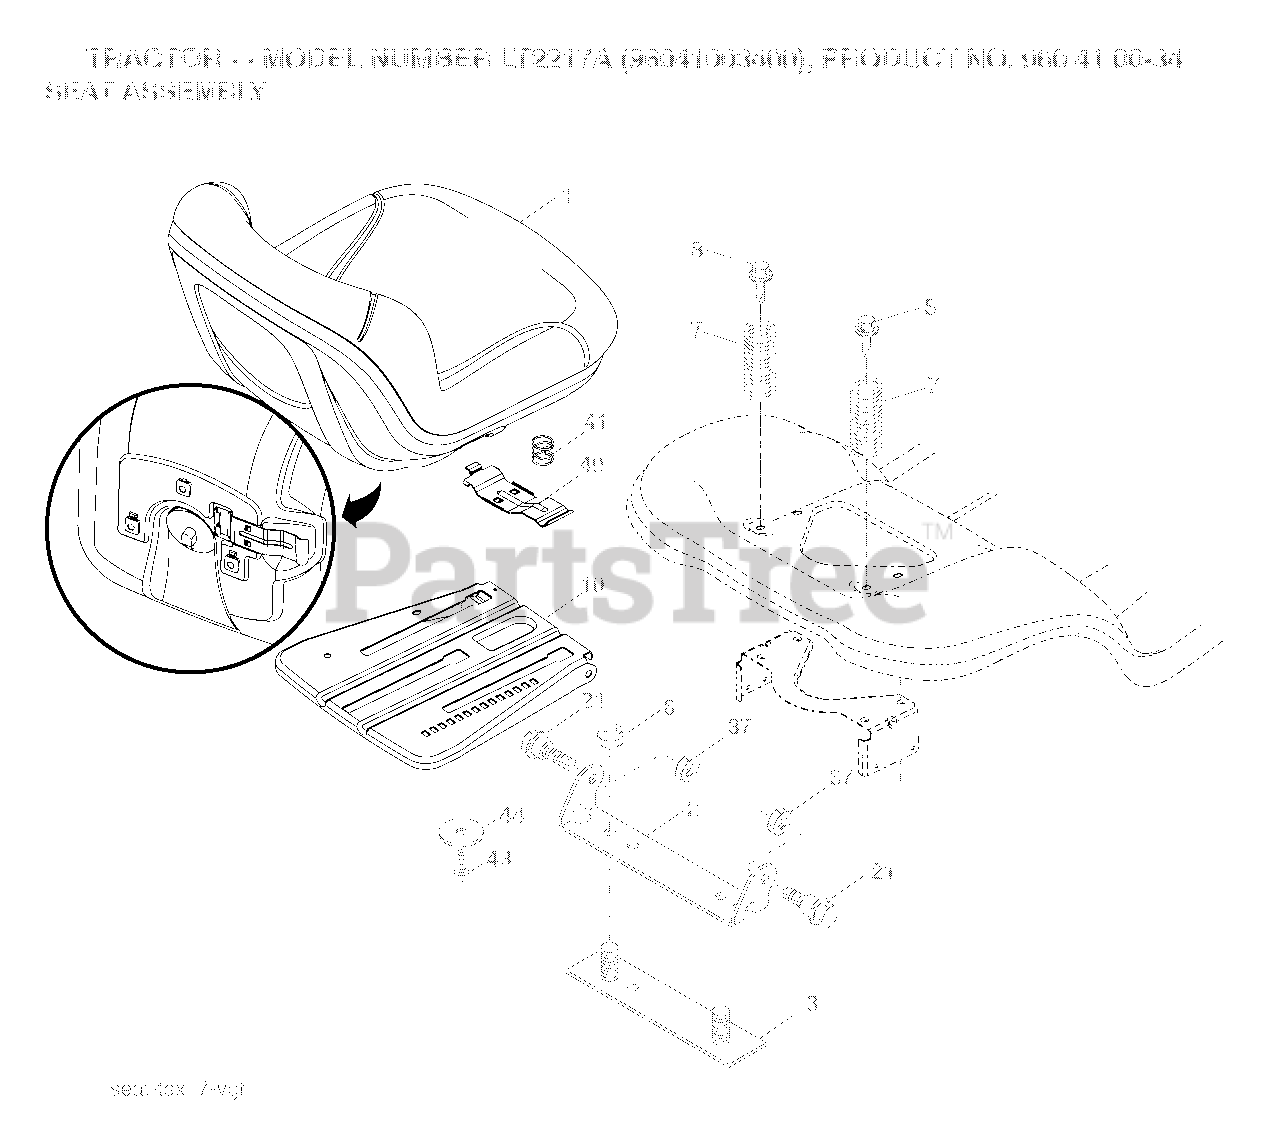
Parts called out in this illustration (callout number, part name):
1	SEAT.TG150.BLK.NLOGO.
2	BRKT.PIVOT.FENDER
6	NUT
7	SPRING COMPRESSION
8	BOLT, 5/16-18 X 1 3/4
10	PAN.ASM.SEAT.3PT
21	BOLT.SHOULDER.5/16-18
37	NUT.71038.31-18.HEX.NYLOCK
40	HANDLE.SLIDE.SEAT.TEX.BLACK
41	SPRING.LATCH.SEAT.TEX
44	WASHER 13/32 X 2-3/8 X 12GA
